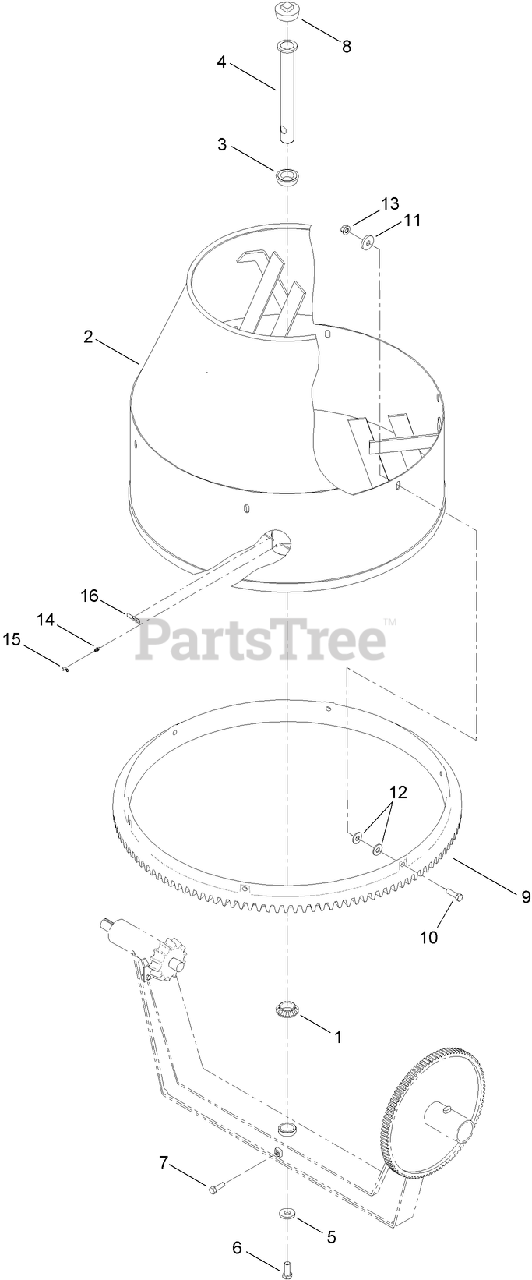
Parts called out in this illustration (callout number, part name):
1	BEARING-ROLLER
3	BEARING
4	SPINDLE
5	WASHER-FLAT
6	SCREW-HH
7	SCREW-HH
9	GEAR-RING
10	SCREW-HH
11	WASHER-FLAT
12	WASHER-FLAT
13	NUT-LOCK
14	FITTING
15	CAP-PLUG
16	DECAL-GREASE
